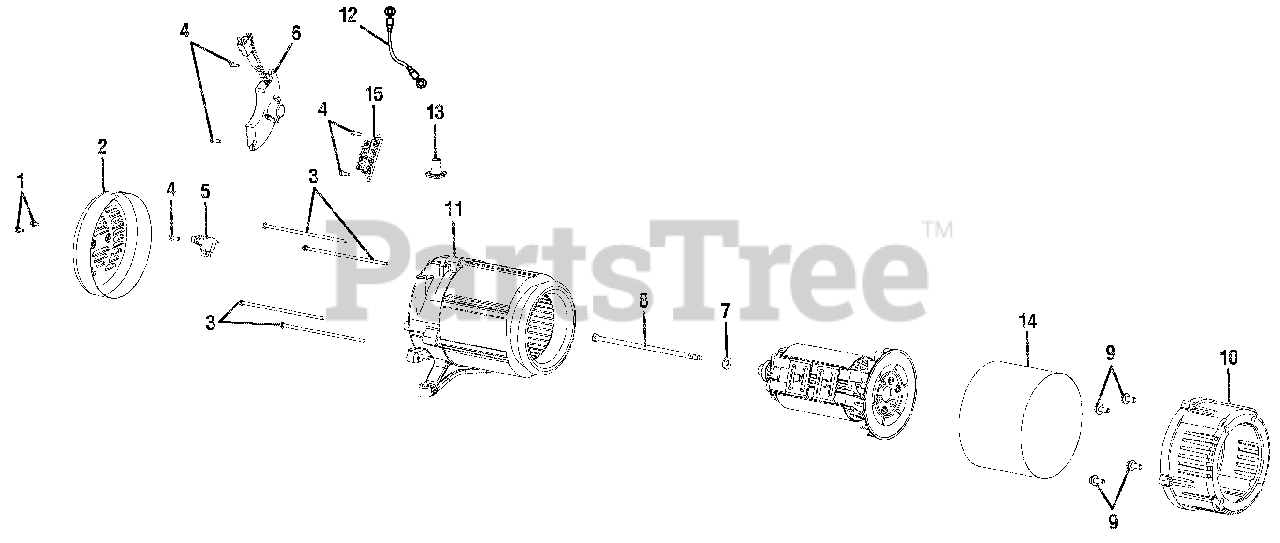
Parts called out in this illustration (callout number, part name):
1	BOLT (M5 X 10 MM FLANGEHEX HD)
2	BRUSH COVER
3	BOLT (1/4-20 X 6 IN. HEX HD.)
4	BOLT (M5 X 16MM FLANGE HEX HD)
5	BRUSH ASSEMBLY
6	AUTOMATIC VOLTAGE REGULATOR
7	WASHER (5/16 IN.)
8	BOLT (5/16-24 X 230 MM HEX HD)
9	BOLT (3/8-16 X 1-1/4 IN.)
10	ENGINE ADAPTER
11	PARTS MANUAL GV905011A
12	BONDING WIRE
13	RUBBER BOOT
15	TERMINAL BLOCK
